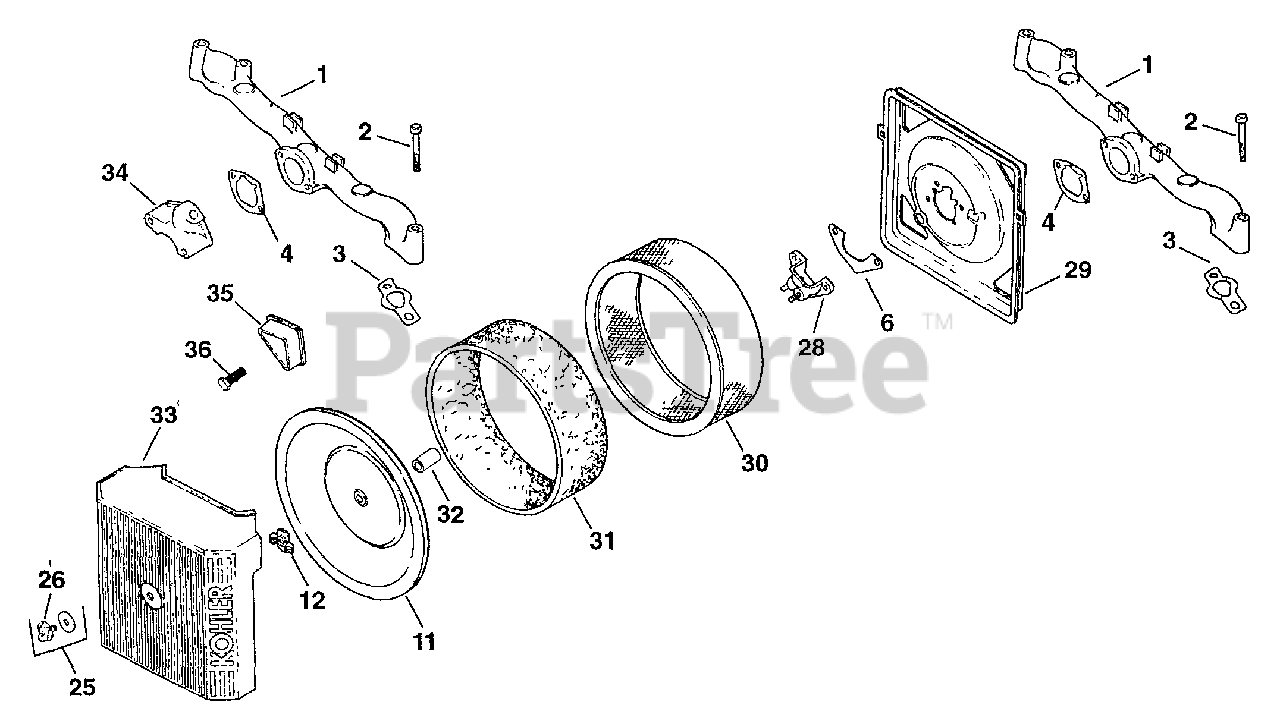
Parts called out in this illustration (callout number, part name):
1	MANIFOLD, INTAKE
2	Screw, hex. flange M6x1.0x55
3	GASKET, INTAKE MANIFOLD USE 24 041 79-S
4	GASKET, AIR CLEANER BASE
6	GASKET, FUEL SPITBACK CUP
11	COVER, INNER AIR CLEANER
12	NUT, WING
25	KIT - USE 54 755 01
26	KNOB - USE 25 341 03
28	CUP - USE 24 109 09
29	BASE - USE 24 094 18
30	ELEMENT, AIR FILTER (HIGH) - Also available Retail Packaged 24 883 03-S1 Air Filter Kit
31	PRE-CLEANER (HIGH)
32	SEAL, BREATHER
